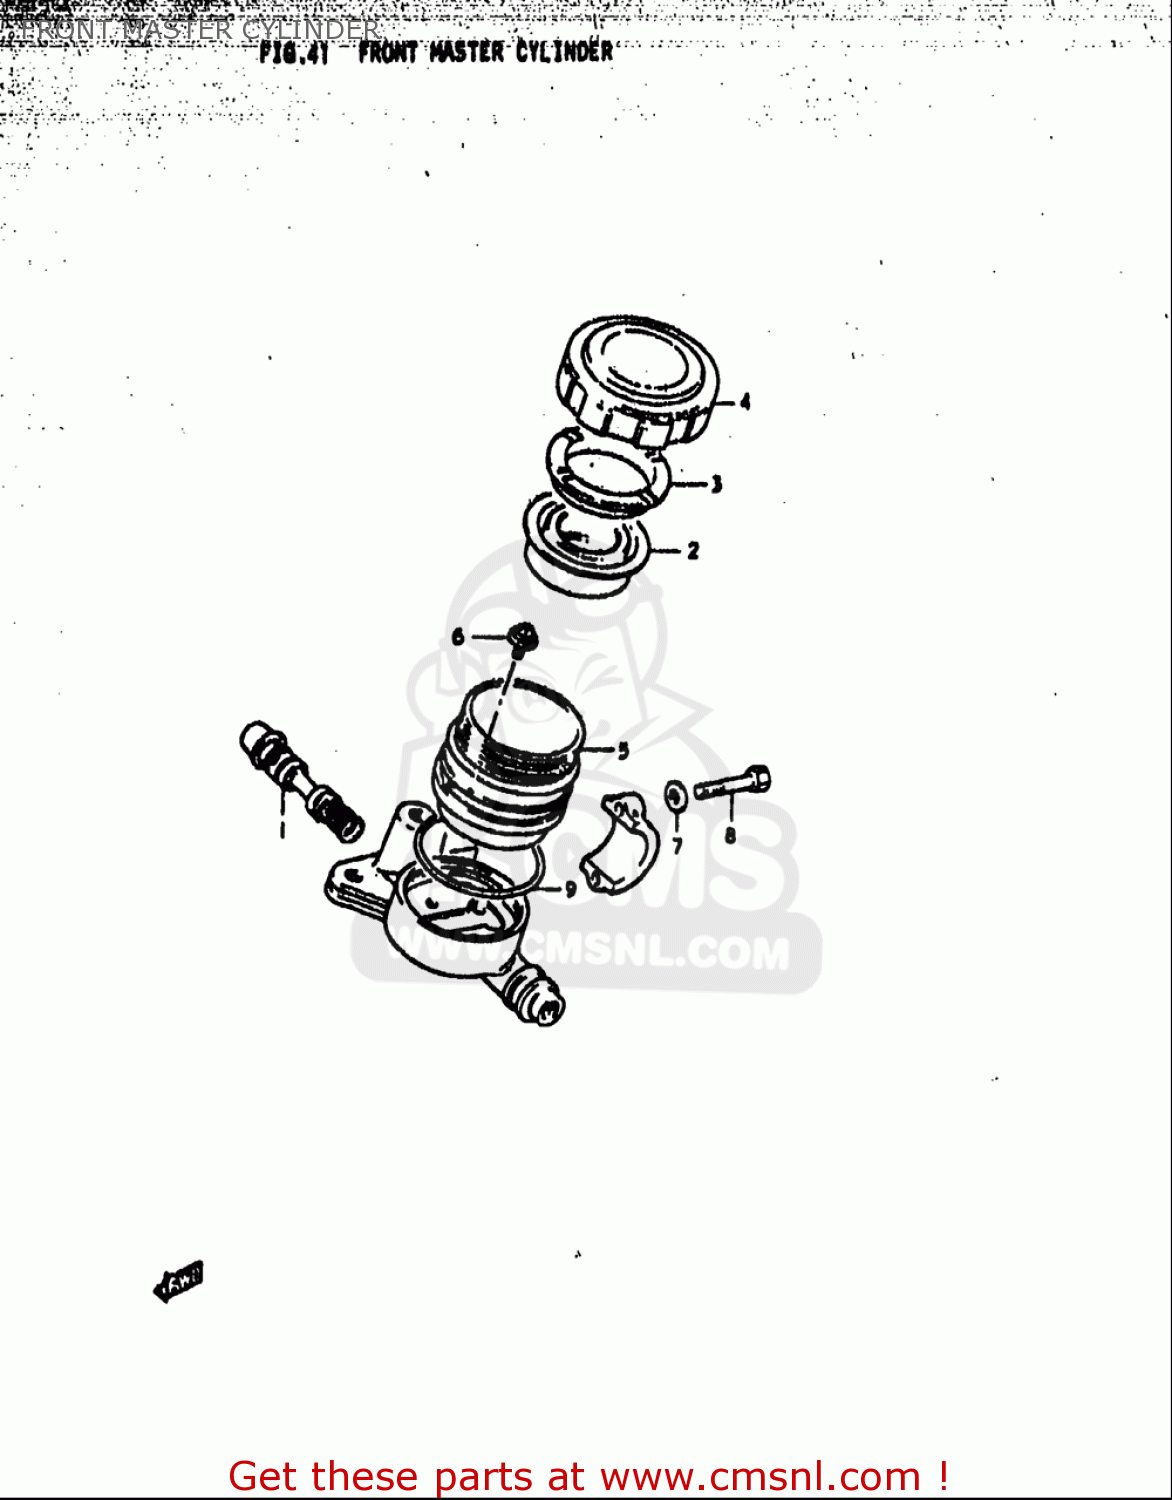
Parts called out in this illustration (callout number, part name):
1	PISTON & CUP SET
2	DIAPHRAGM
3	PLATE
4	CAP
5	RESERVOIR
7	WASHER
8	BOLT
9	O RING
